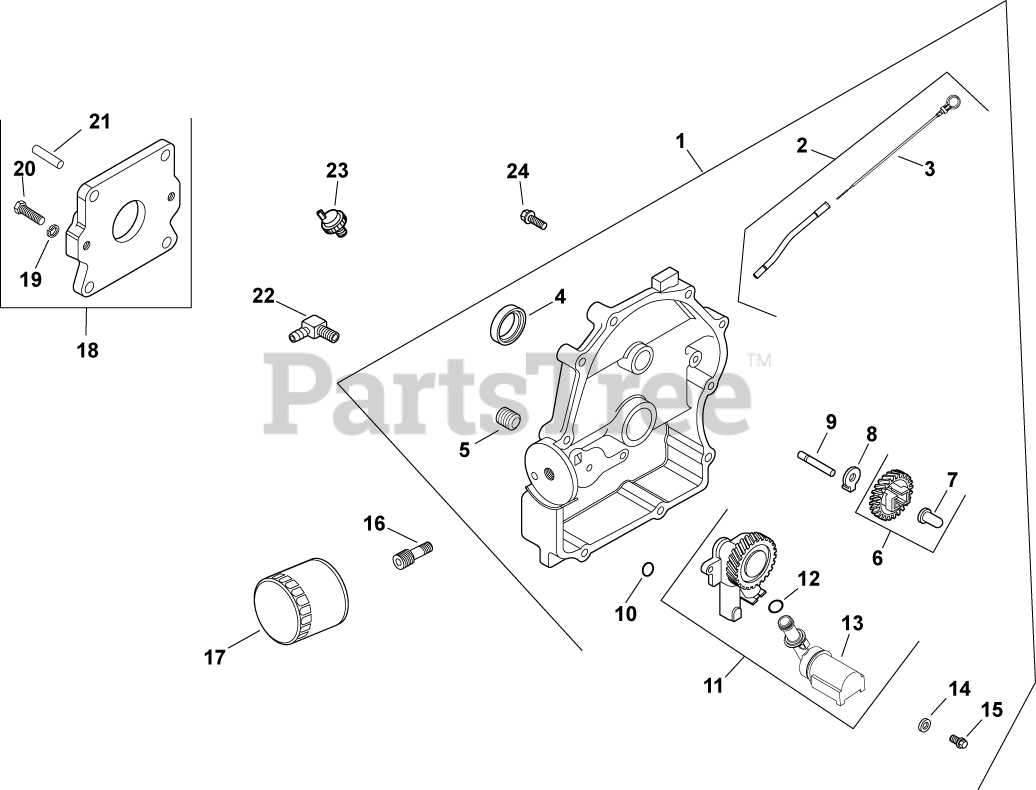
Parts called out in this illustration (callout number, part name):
1	PLATE, CLOSURE & BEARING USE 24 009 227-S
2	KIT, DIPSTICK/DIPSTICK TUBES
4	SEAL, OIL
5	PLUG, CTSK PIPE 1/8"
6	KIT, GOVERNOR GEAR W/PIN
7	PIN, GOVERNOR REGULATING
8	TAB, LOCKING
9	SHAFT, GOVERNOR GEAR
11	PUMP ASSEMBLY, OIL-USE 24 393 53-S
12	O-RING, OIL PICK-UP
13	PICK-UP, OIL
14	SCREW,FLG THD FRM M6X1.0X25-(#25086395S)
15	WASHER, FLAT 6 MM
16	NIPPLE, OIL FILTER
17	OIL FILTER
18	KIT, PUMP ADAPTER
19	WASHER, SPRING LOCK 7/16"
20	SCREW,CAP HD 7/16-14x1 1/2"
21	PIN, ALIGNMENT
22	CONNECTOR, 90 DEG. HOSE
23	SENSOR, OIL PSI
24	SCREW, FLG M8X1.25X45
